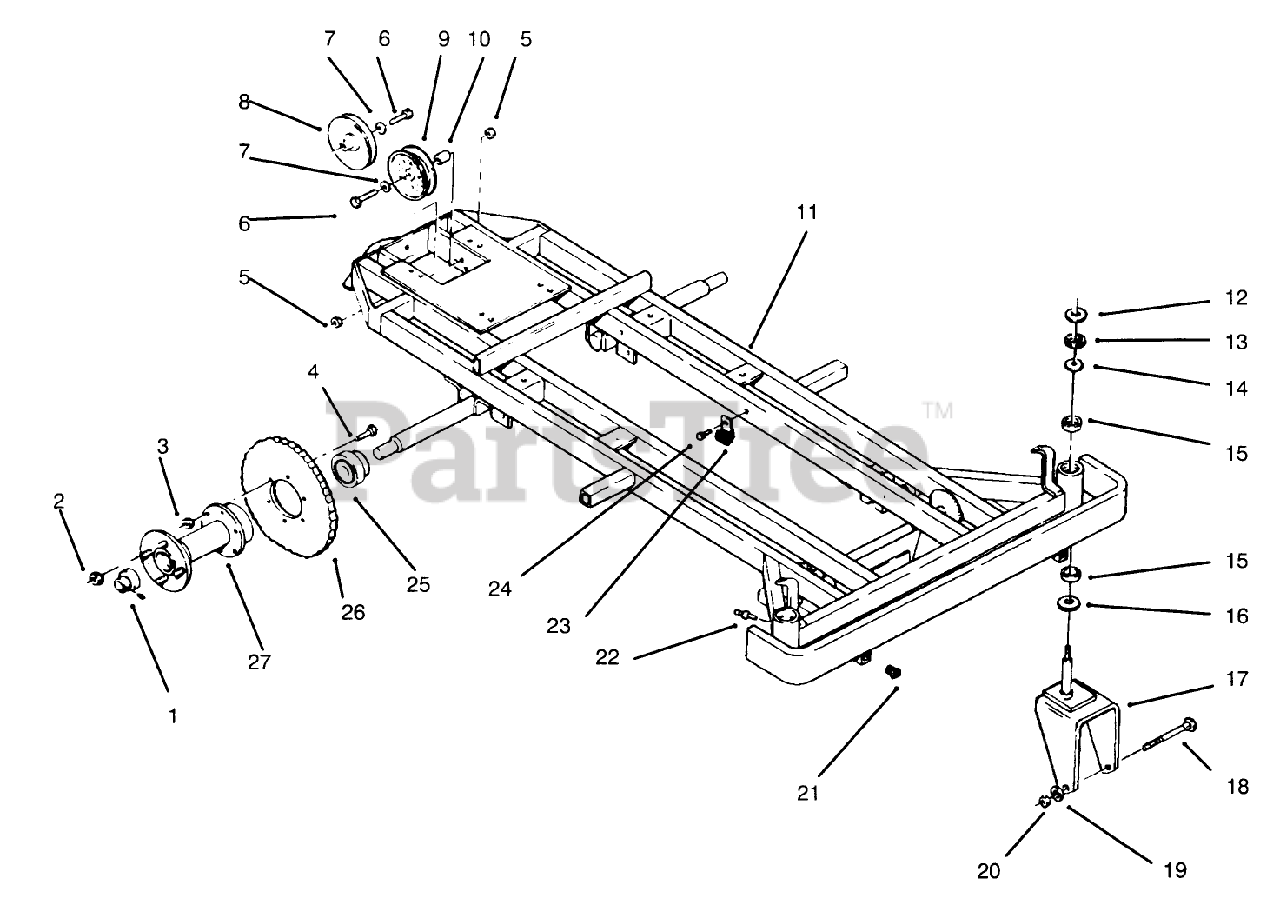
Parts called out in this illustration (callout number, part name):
1	BEARING-REAR AXLE
2	NUT-LUG
3	NUT-LOCK, NI
4	SCREW-HH
5	NUT-LOCK, NI
6	SCREW-HH
7	WASHER-FLAT
8	PULLEY-IDLER V
9	PULLEY FLAT B
10	BUSHING
11	WLDMT-FRAME B
12	RING-RETAINING
13	WASHER-THRUST
15	BUSHING PIVOT
16	WASHER-THRUST
17	Fork-Front Wheel
18	SCREW-HH
19	WASHER-LOCK
20	NUT-HEX
21	PLUG-SQUARE PLASTIC
22	FITTING-GREASE
23	CLIP
24	SCREW-HWH
25	BEARING-REAR AXLE
26	SPROCKET-REAR HUB B
27	Hub-Rear Wheel (Incl. Ref. #22)
